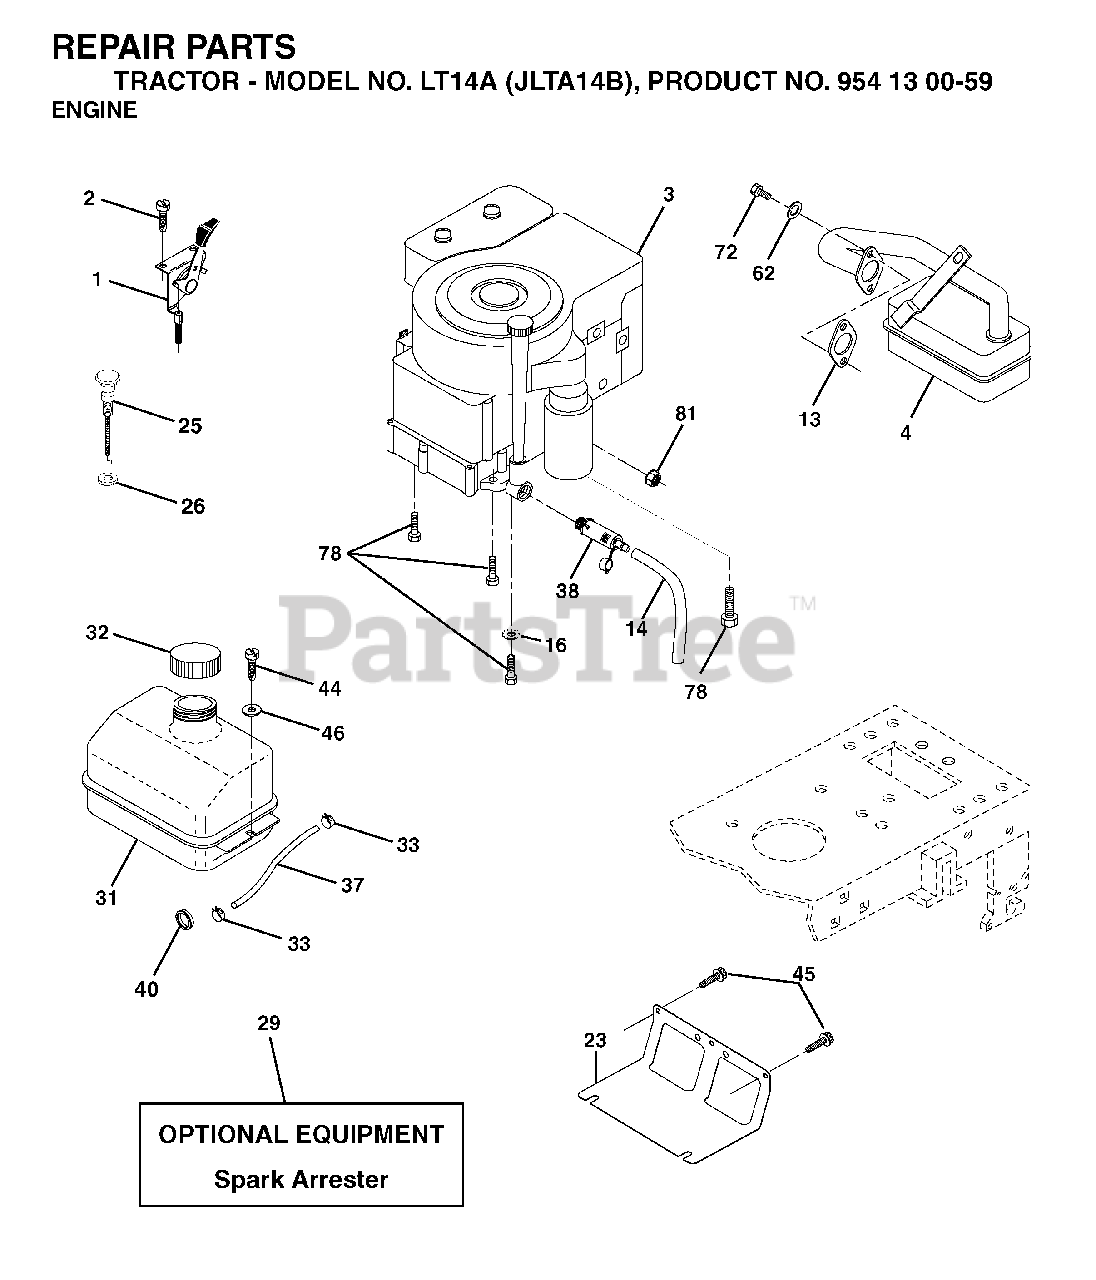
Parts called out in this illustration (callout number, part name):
1	CONTROL TH/CH FLAG
2	SCREW
13	REPL BY 532 27 22-93
14	TUBE, DRAIN OIL ASM.
16	LOCKWASHER
23	SHEILD.BROWNING.DBR.GUARD
26	NUT KEPS 3/8 - 24 UNF
29	ARRESTER SPARK (OPTIONAL)
32	FUEL CAP
33	HOSE CLAMP
37	LINE.FUEL.20
38	PLUG DRAIN OIL EASY
40	GROMMET T
44	SCREW HEXWSHR 1/4-20X3/4
45	SCREW, 3/8-16X3/4
62	LOCKWASHER
72	SCREW
78	SCREW.3/8-16
81	NUT
